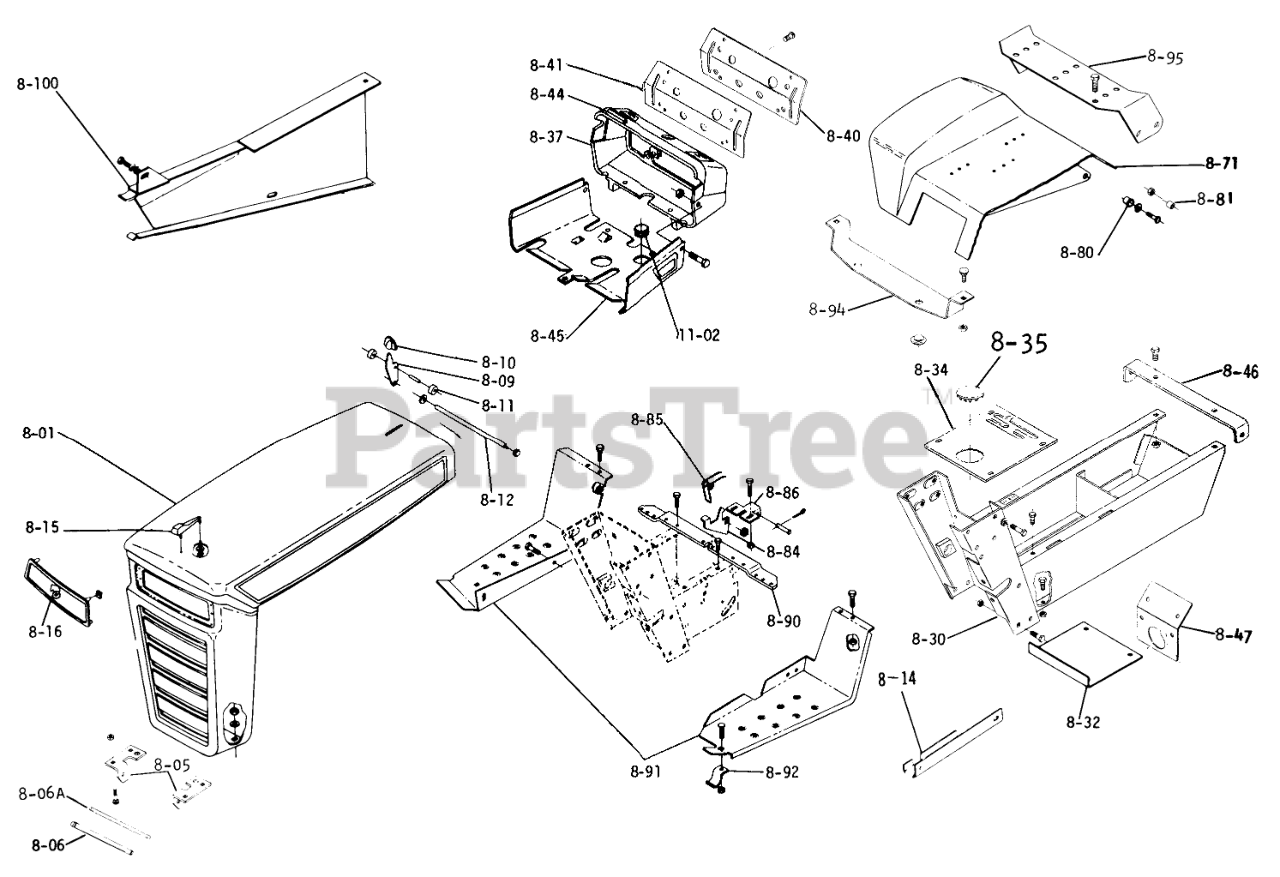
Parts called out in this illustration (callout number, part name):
8-01	Hood Assy.
8-05	Bracket-Grille-R.H.
8-06	GRILL PIVOT ROD
8-06A	ROD-HOOD STOP
8-09	LEVER HOOD LATCH
8-10	KNOB
8-11	Roller
8-12	Rod Latch
8-14	Channel
8-15	Hood Ornament
8-16	ESCUTCHEON PLATE
8-30	Hoodstand Assy.
8-32	Cover-Dust
8-34	Cover Plate
8-35	Plug Button
8-37	Housing
8-40	Dash Panel
8-41	BACK UP PLATE
8-44	Tape
8-45	Support-Tank
8-46	Bracket
8-47	Instrument Backet
8-71	Fender
8-80	BUSHING-FLANGED
8-81	SPACER
8-84	Fender Latch
8-85	Spring
8-86	BRACKET FENDER LATCH
8-90	Bracket-Footrest
8-91	Footrest-RH
8-92	BRACKET
8-94	Fender Bracket
8-95	Bracket Fender Hinge
8-100	Machine Bushing
